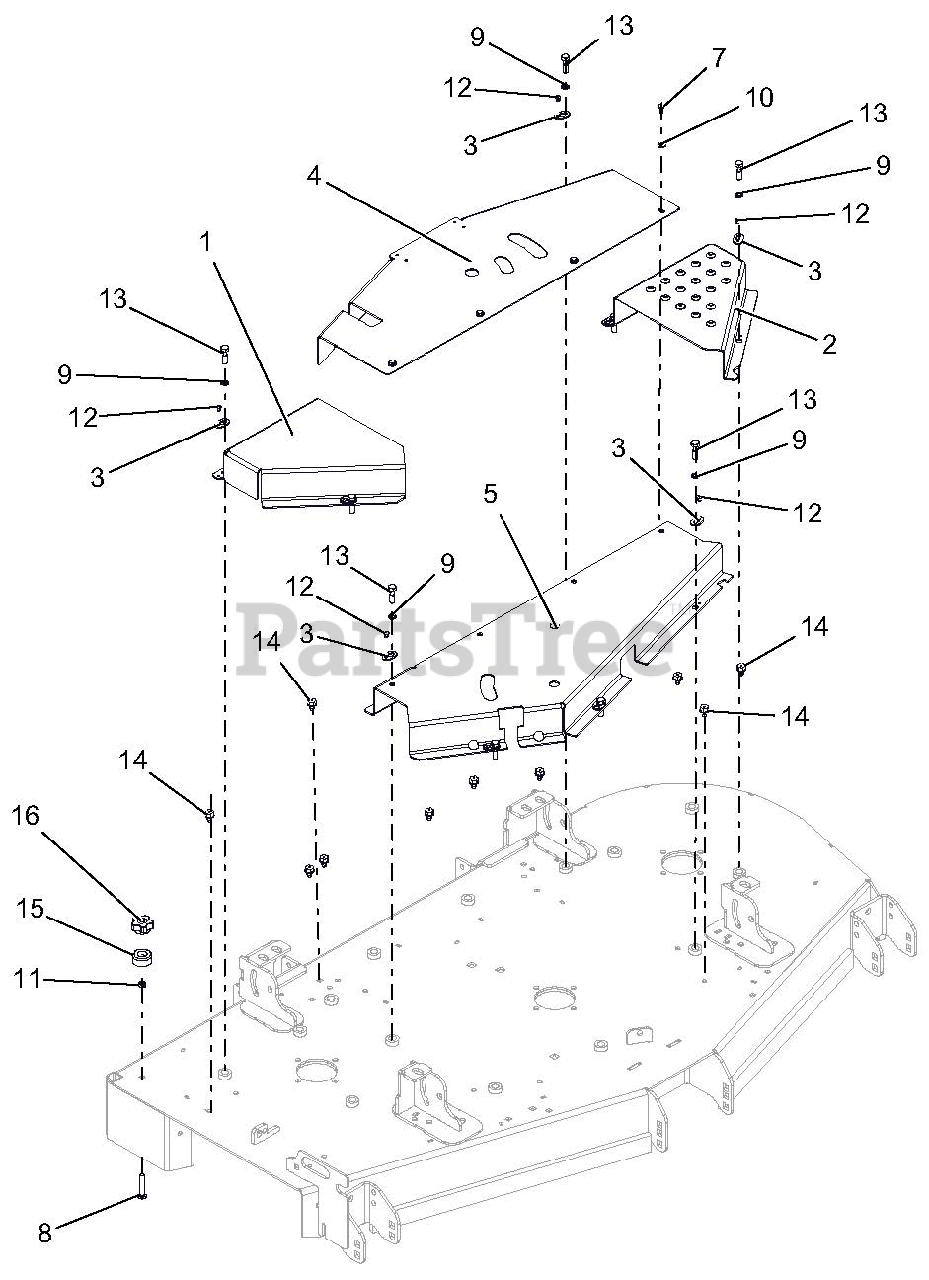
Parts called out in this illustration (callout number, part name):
1	GUARD, RH PT200 CE BELT
2	GUARD, LH PT200 CE BELT
3	KEEPER, BOLT
4	BRKT, REAR BELT GUARD CE-60
5	WLDMT, FRONT BELT GUARD CE-260
7	BLT-HEX .25-20X.50 GR5 YWZC
8	BLT-RDHDSQNK .31-18X2.0 FTH G5 Y
9	LOCK, WSHR-EXT 0.391 X 0.628 X 0.036 YWZC
10	WSHR-FL-STL.281X.62X.065 YWZC
11	NUT-LK-CTR .31-18 YWZC
12	RVT-POP .187x.250 (#64) YWZC
13	BLT, HEX 0.38-16 X 1.25 GR5 CAPTIVE
14	SCR-TAP .38-16X.50 HWH TR YWZ
15	BUMPER, RECESSED 1.50 X .63 W/.31 HOLE
16	KNOB, CLAMPING
